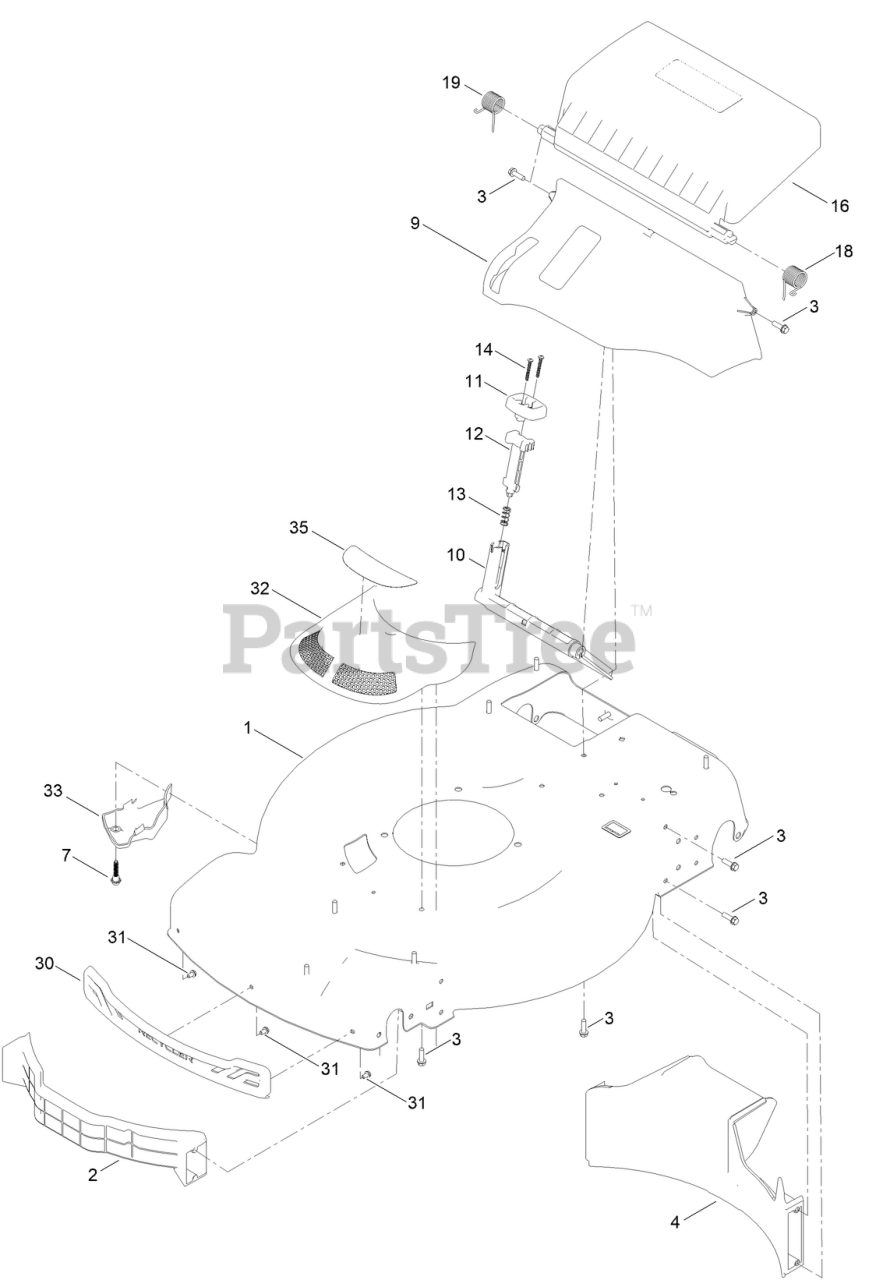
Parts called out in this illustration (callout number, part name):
1	HOUSING ASM
2	BAFFLE-FRONT, DOMESTIC
3	SCREW-HWH
4	BAFFLE-REAR, RWD
7	SCREW-SHOULDER,HWH
9	ASM-CHUTE, IN MOLD
10	DEFLECTOR-RECYCLE
11	KNOB-RECYCLE
12	LATCH-RECYCLE
13	SPRING-COMPRESSION
14	SCREW-PPH
16	ASM-REAR DOOR, IN-MOLD (60V)
18	SPRING-TORSION, LH
19	SPRING-TORSION, RH
30	BUMPER-FRONT
31	SCREW-PLASTIC, HWH
32	ASM-INTAKE, RWD
33	COVER-INTAKE, BOTTOM
35	DECAL-60V VORTEX TECHNOLOGY
